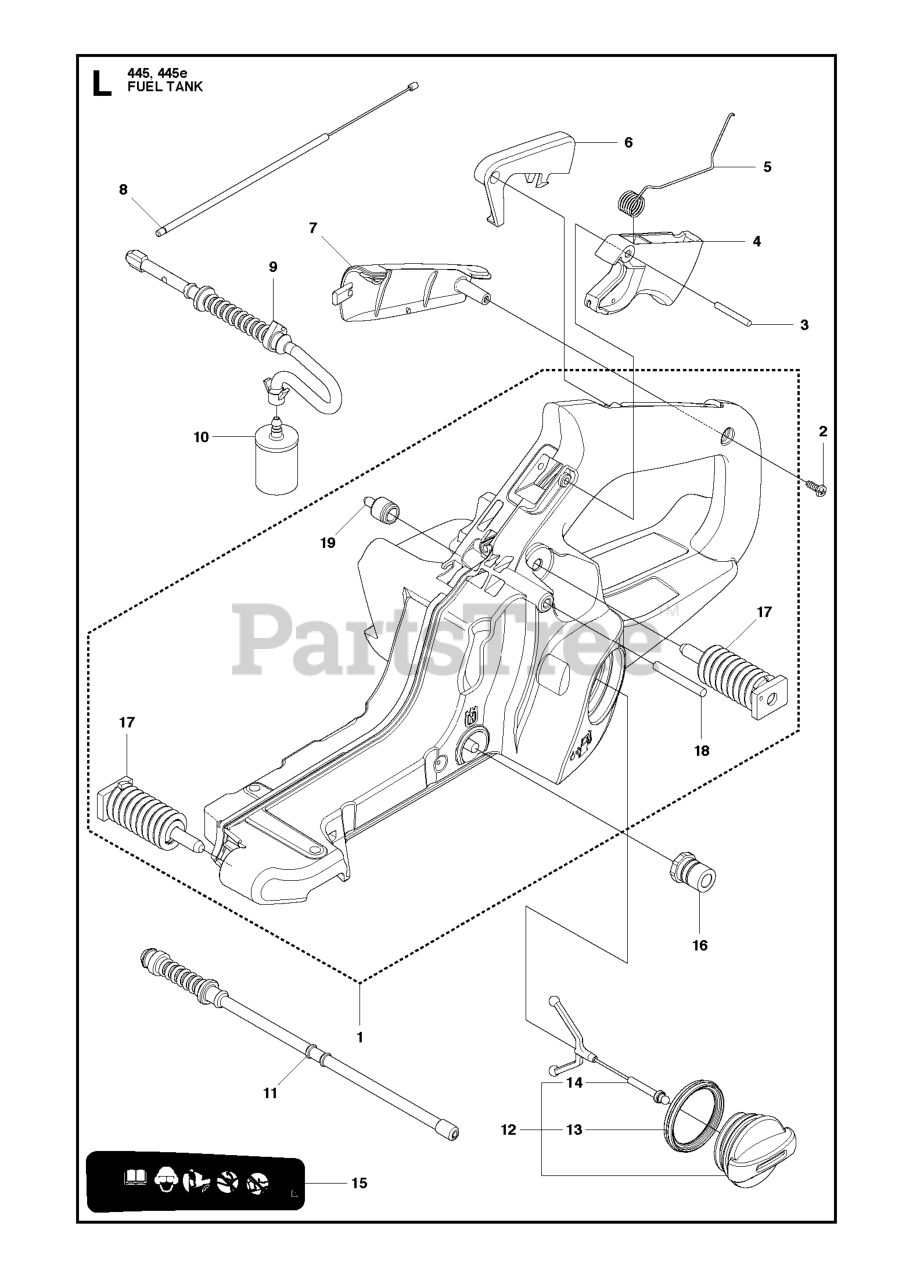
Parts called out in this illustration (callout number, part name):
1	FUEL TANK ASSY
4	THROTTLE TRIGGER
6	THROTTLE LOCKOUT
7	HANDLE INSERT
8	THROTTLE CABLE ASSY
10	RP FUEL FILTER
11	RETURN HOSE
12	ASSY TANK CAP GREY
16	LATERAL SUPPORT
17	ANTI VIBRATIONS ELEMENT
18	GROOVED PIN
19	FUEL TANK VENT
